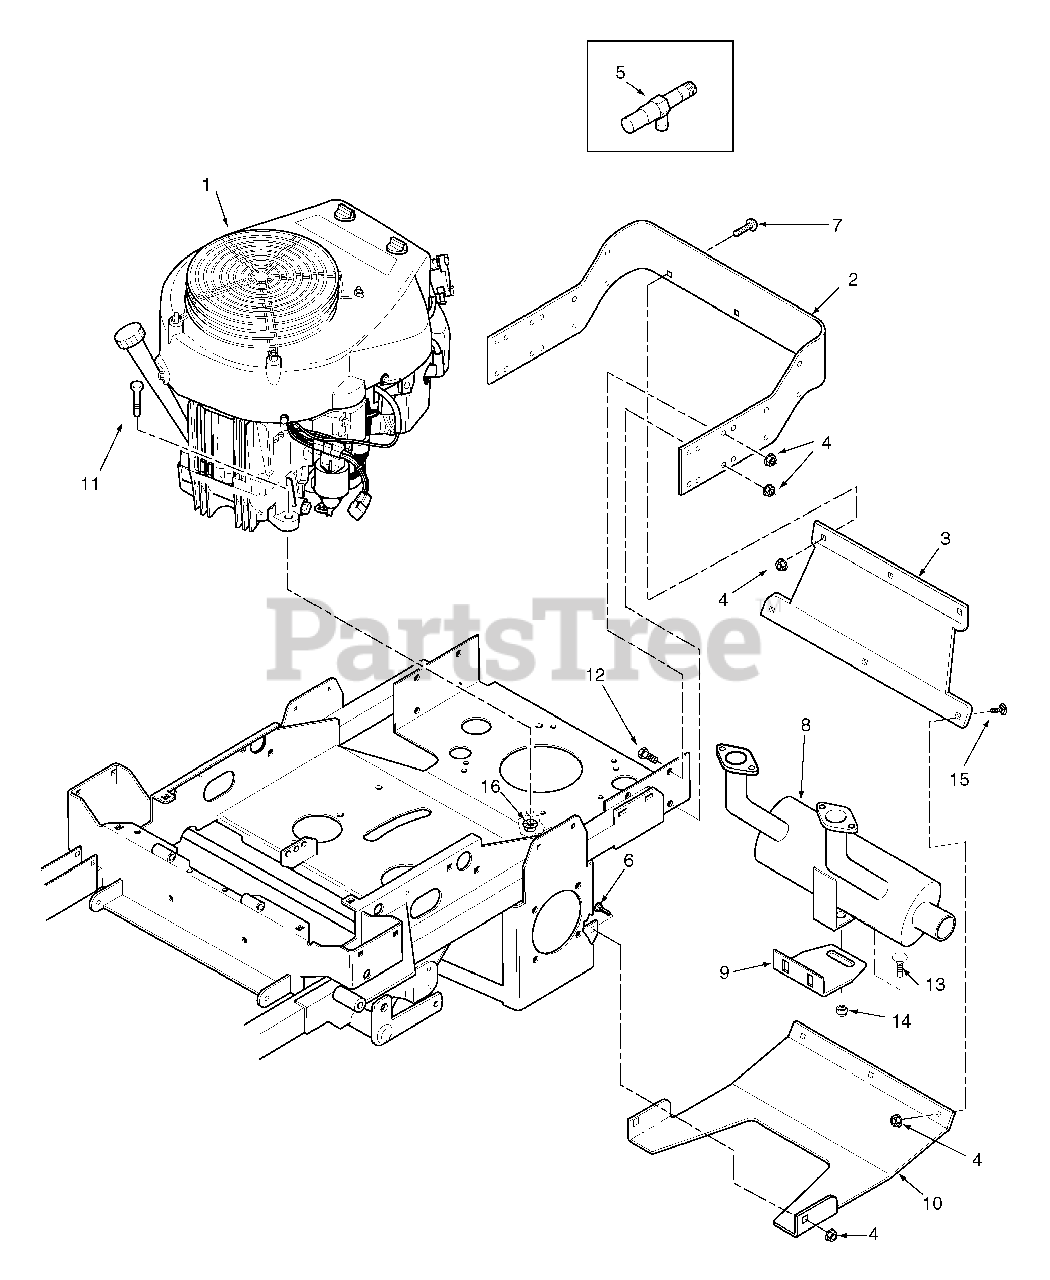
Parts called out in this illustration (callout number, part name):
1	Engine, 27HP Kohler
2	Bumper, Rear
3	Weight, Rear (Shield) 61A Only
4	Nut, Serr. Flange 3/8-16
5	Extension, Oil Drain 4" - Kohler
6	Bolt, Carr. 3/8-16 x 1"
7	Bolt, Hex Head 3/8-16 x 1-1/4"
8	Muffler - Kohler
9	Bracket, Muffler
10	Plate, Skid
11	Bolt, Hex Head 5/16-18 x 1-1/2"
12	Bolt, Hex Head 3/8-16 x 1"
13	Bolt, Hex Head 5/16-18 x 3/4"
14	Nut, Serr. Flange 5/16-18
15	Bolt, Hex Head 3/8-16 x 1-1/4"
16	Nut, Serr. Flange 5/16-18
